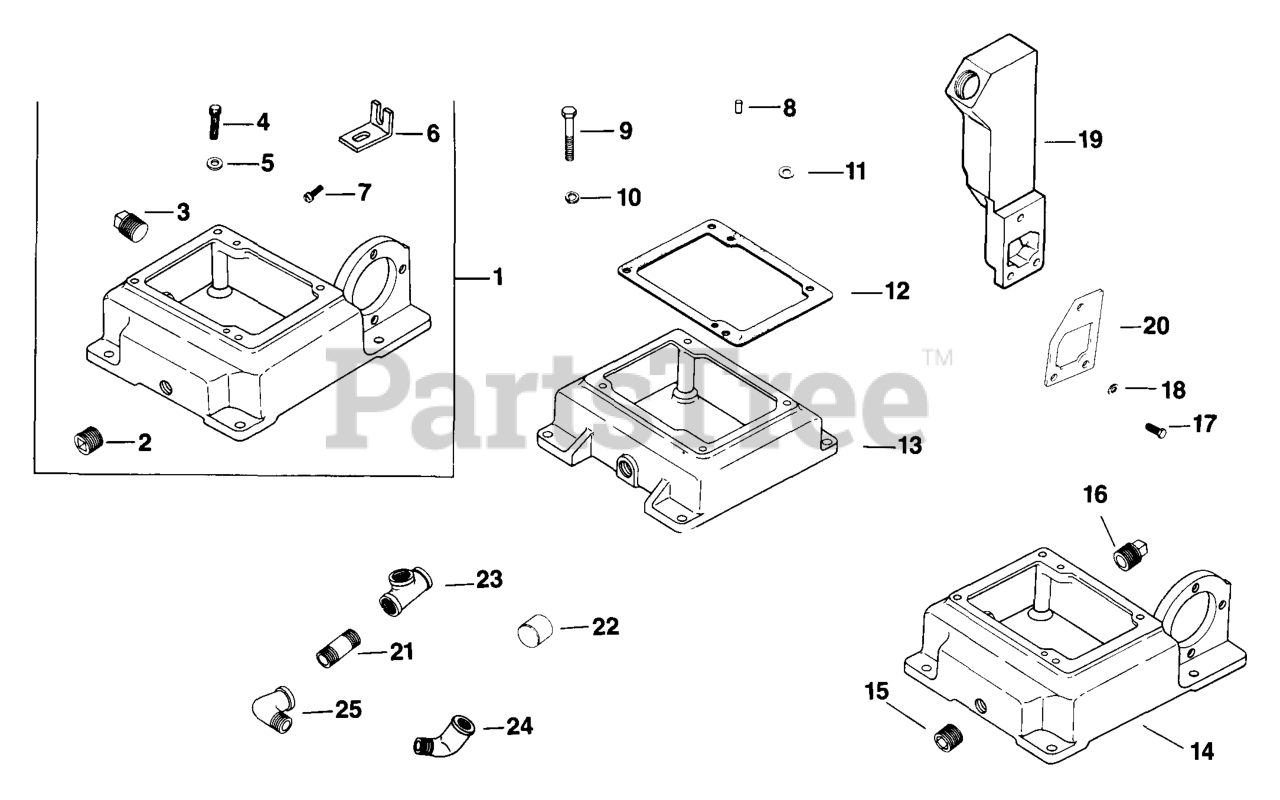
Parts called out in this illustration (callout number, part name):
10	WASHER, SPRING LOCK 3/8"
12	GASKET - DISCONTINUED
13	OIL PAN - DISCONTINUED
21	NIPPLE - DISCONTINUED
22	CAP - DISCONTINUED
